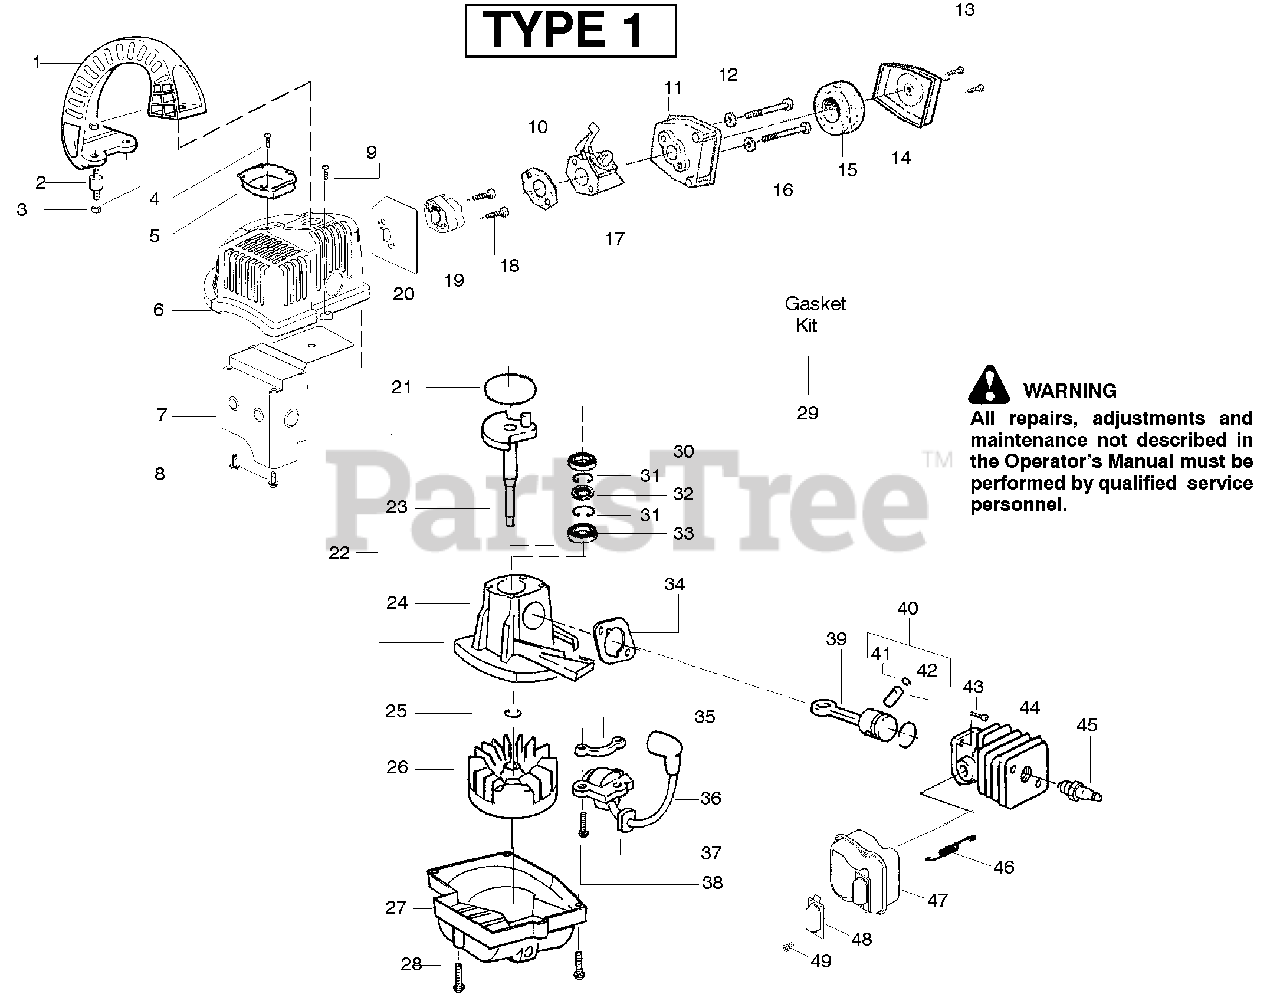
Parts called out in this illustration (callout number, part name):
2	Isolator-Handle
4	Screw
5	Plate-Crankcase
7	Shield-Heat
8	Screw
10	Gasket-Carb. (Kit)
14	Cover-Air Box
15	Foam-Air Filter
17	Kit-Carburetor Ass'y. (W-12)
17	Kit-Carburetor Ass'y. (C1U-W12A)
19	Adaptor-Carb.
20	Gasket-Cyl/Carb. Adaptor (Kit)
21	Gasket-C'case/Shroud (Kit)
22	Assy.-C'case & C'shaft
23	Assy.-Crankshaft
24	Assy.-Crankcase
25	Retainer Ring (C'shaft)
26	Assy.-Flywheel
27	Fan Housing
28	Screw
29	Kit-Gasket
30	Inner Bearing
31	Retainer Ring (C'case)
32	Seal-Crankcase
33	Bearing-Outer
34	Gasket-Cylinder (Kit)
35	Spacer-Ign. Module
36	Ignition Module
37	Grommet-Ign. Module
39	Kit-Connecting Rod Assy.
40	Kit-Piston
41	Wrist Pin Retainer
42	Piston Ring
44	Kit-Cylinder
45	Spark Plug (RCJ-6Y)
46	Spring-Muffler
47	Assy-Muffler
48	Kit-Spark Aresstor
